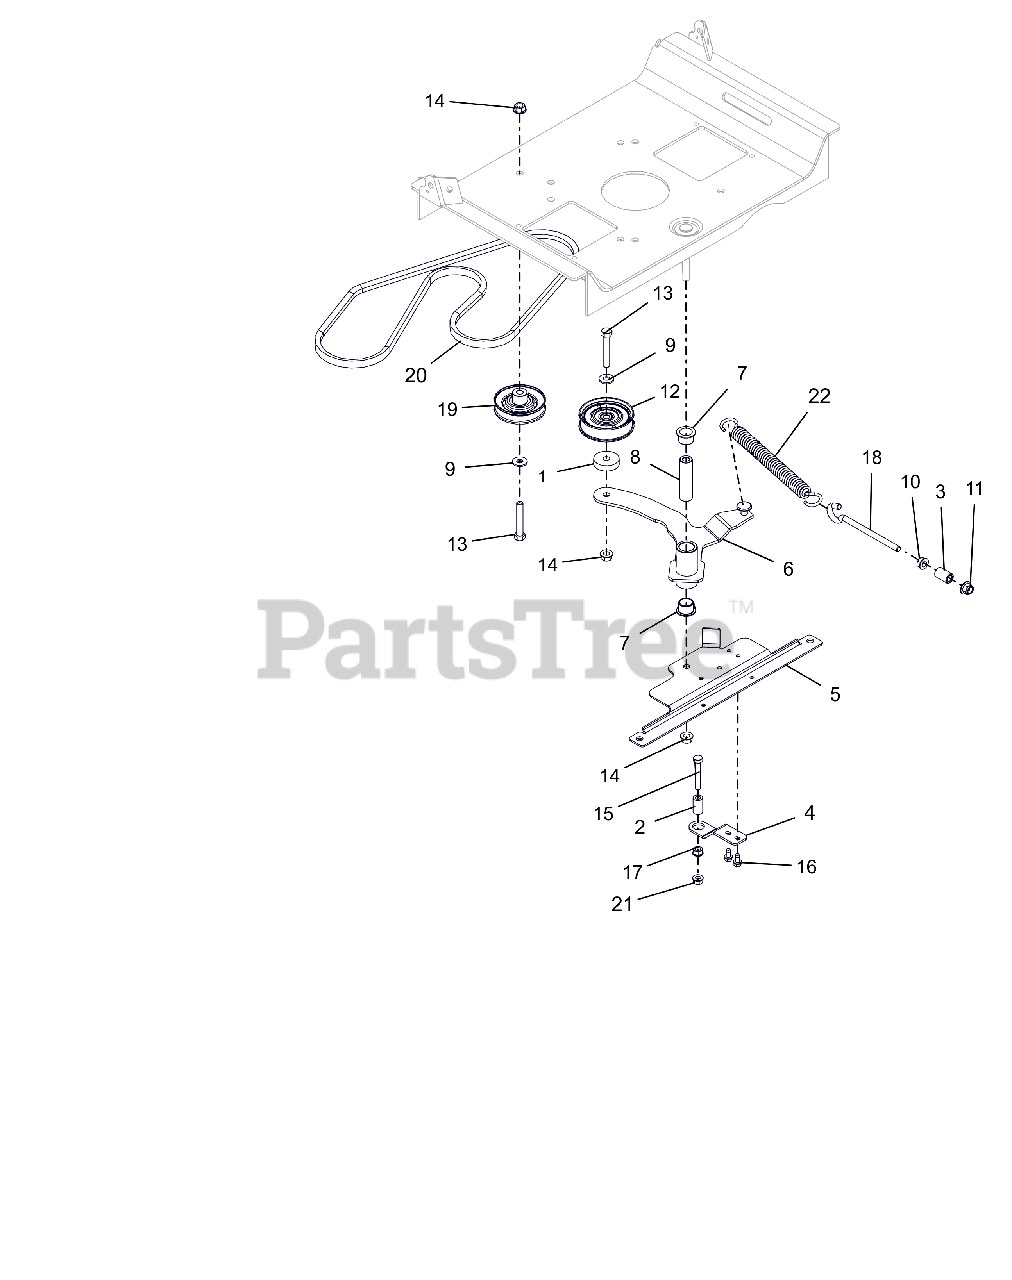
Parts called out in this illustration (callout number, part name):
1	SPACER, .39 X 1.50 X .380
2	SPACER, RUBBER 5/16 IDX1.0 LG
3	SPACER, .375X.625X.970 (PM)
4	BRKT, CLUTCH STOP
5	BRKT, IDLER ATTACHMENT
6	WLDMT,GRD DRIVE IDLER ARM-LGR
7	BSHG-FLG 0.75X0.875X.625X1.125
8	BUSHING, SLEEVE .38X.750X2.78
9	WSHR,FLT .375X.875X.083 ZCC
10	NUT, SPNLK-FLG .38-16 G5 ZCC
11	NUT,NYL-FLG .38-16 GF ZCC
12	IDLER, FLAT - 3.05" X .75"
13	BLT,HEX .38-16X2.25 G5 ZCC
14	NUT-LK-TOP-FLG .38-16 ZC120
15	BLT, HEX .31-18X2.00 G5 ZCC
16	SCR-TAP .25-20X.50 HWH ZCC
17	NUT,SPNLK-FLG .31-18 G5 ZCC
18	BOLT,.38-16 X 4.25-.62 DIA EYE
19	IDLER, V-3.000 OD
20	V-BELT, A-RAW EDGE
21	NUT-LK-TOP-FLG .312-18 GF ZCC
22	SPRING, EXTENSION
